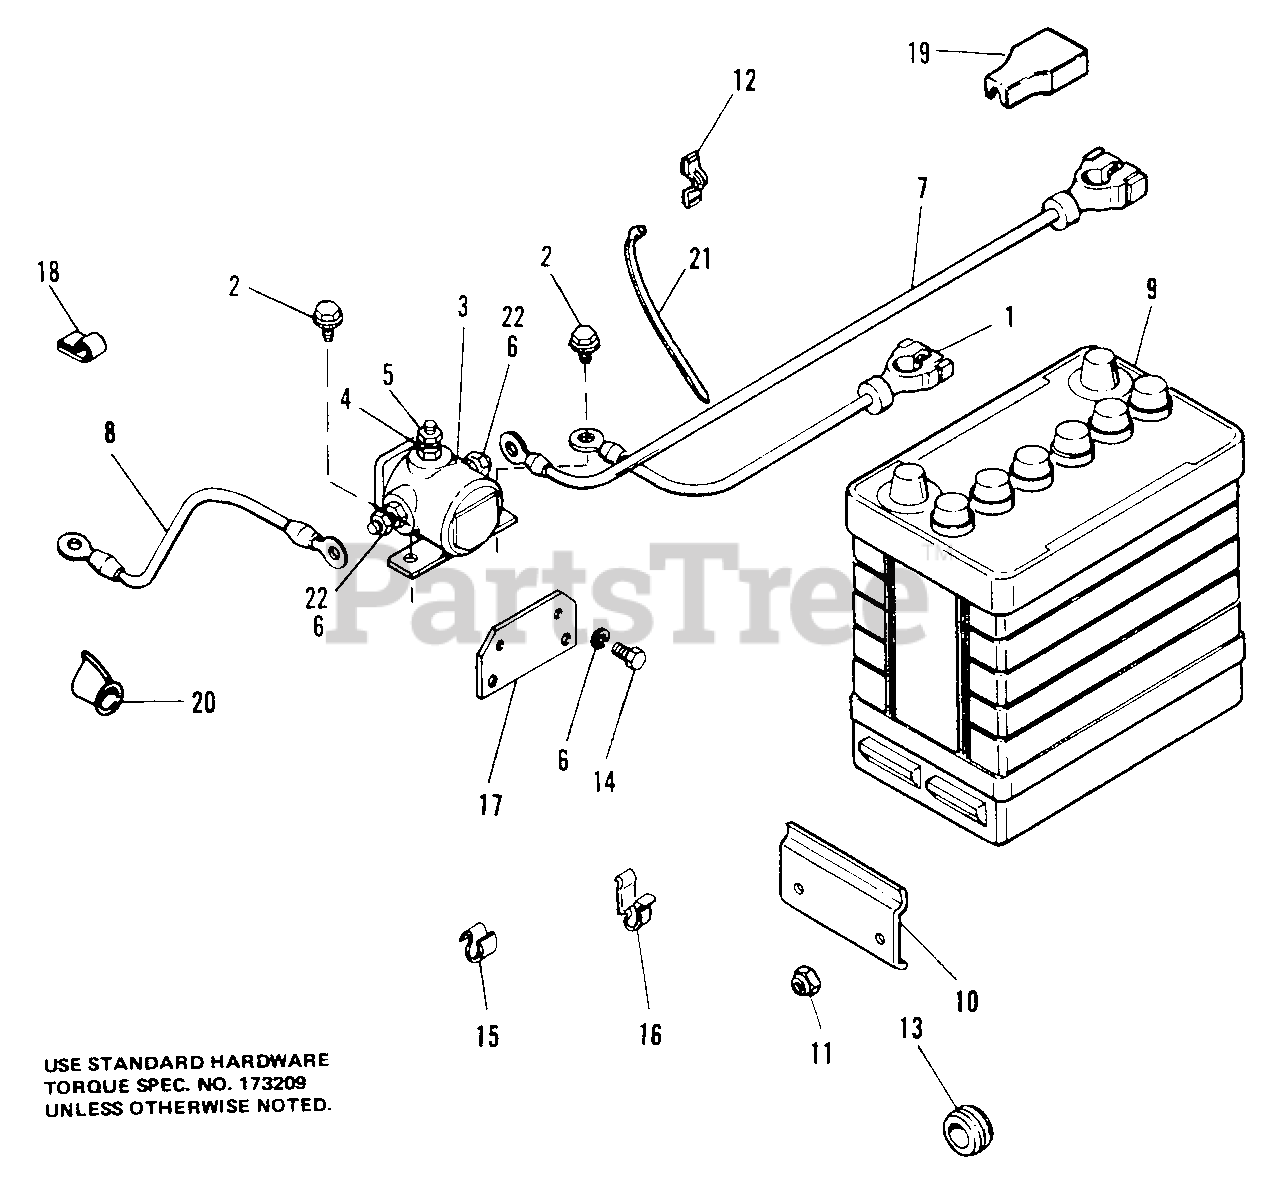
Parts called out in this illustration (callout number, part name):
1	CABLE, Battery to Ground
2	SCREW, Taptite, 1/4-20 x 1/2
4	LOCKWASHER, No. 10
5	NUT, Hex, No. 10-32
6	LOCKWASHER, 5/16
7	CABLE, Battery to Solenoid
8	CABLE, Solenoid to Starter
11	NUT, Elastic, 5/16-18
12	CLIP, Wire
14	CAPSCREW, Hex Hd., 5/16-18 x 3/4
15	CLIP, Tinnermann
16	CLIP. Tinnermann
18	CLIP, Cable
19	PROTECTOR, Terminal
20	COVER, Terminal
21	TIE, Wrap
22	NUT, Hex, 5/16-18
